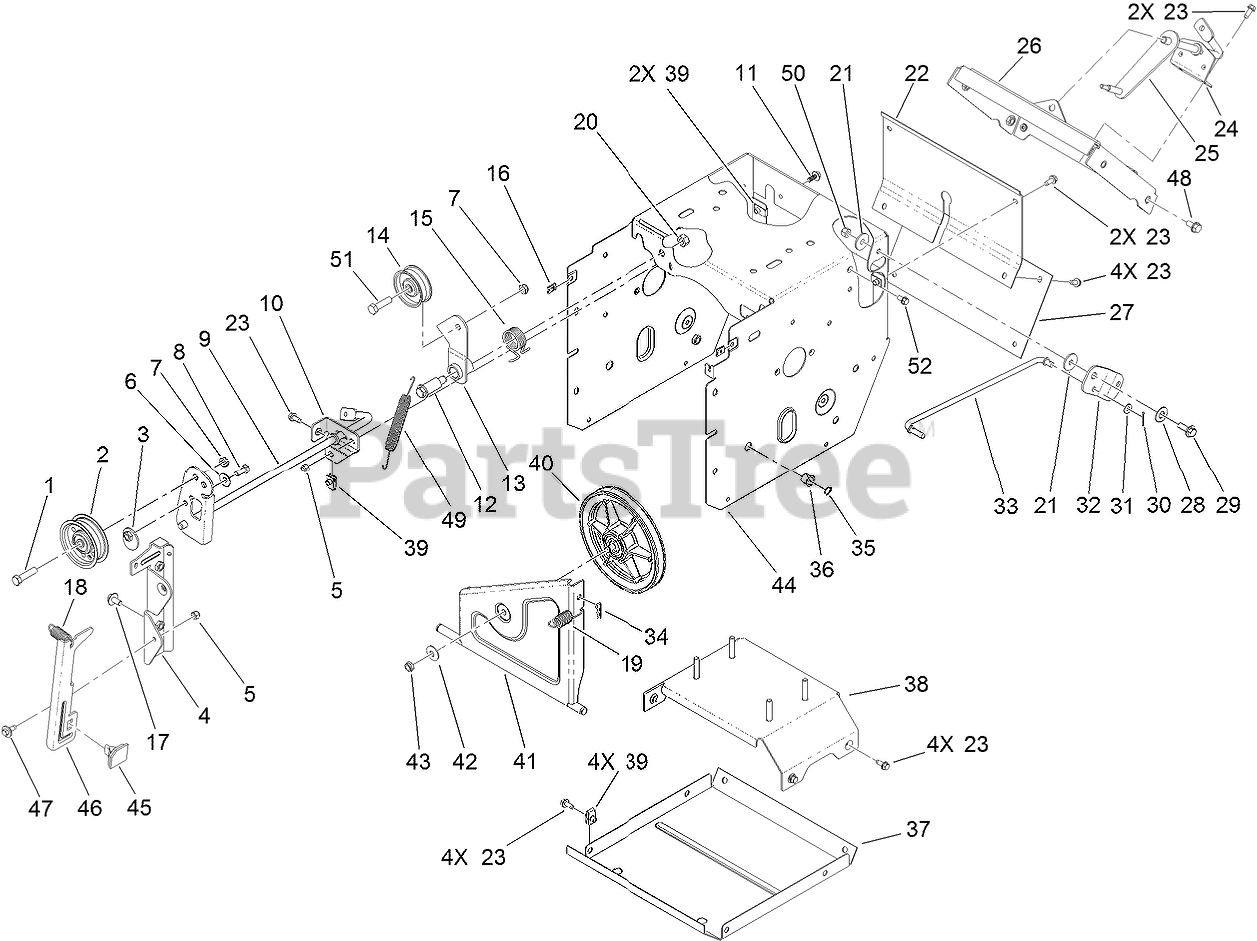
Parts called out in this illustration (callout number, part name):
1	SCREW-HH
2	PULLEY-IDLER
4	BRACKET-IDLER, IMPELLER
5	NUT-LOCK, NI
6	WASHER-BELLEVILLE
7	NUT-LOCK, NI
8	SCREW-HH
9	IMPELLER CLUTCH ASM
10	BRACKET-CLUTCH, IMPELLER
11	SCREW-HHF
12	BOLT-SHOULDER
13	ARM-IDLER, TRACTION
14	PULLEY-IDLER
15	SPRING-TORSION
16	NUT-SPEED, U-TYPE
17	SCREW-HHF
18	SPRING-EXTENSION
19	SPRING-EXTENSION
20	NUT-LOCK, NI
21	WASHER-PIVOT
22	COVER-UPPER
23	SCREW-HWH
24	BRACKET-ROD, SHIFT
25	LEVER-CONTROL, TRACTION
26	SHIFT PLATE ASM
27	COVER-LOWER
28	WASHER
29	SCREW-SHOULDER
30	PIN-COTTER
31	WASHER-PLAIN
32	BELLCRANK-DRIVE
33	LINK-CONTROL, SPEED
34	PIN-COTTER
35	RING-RETAINING
36	BUSHING-NYLINER
37	PAN-BOTTOM
38	FRAME BRACE ASM
40	PULLEY-TRACTION
41	BRACKET-WHEEL, FRICTION
42	WASHER-BELLEVILLE
43	NUT-HEX
44	FRAME-TRACTION
45	PAD-BRAKE
46	ARM-BRAKE
47	SCREW-SHOULDER
48	SCREW-HWHTF
49	SPRING-EXTENSION
50	NUT-LOCK, NI
51	SCREW-HH
52	SCREW-HWH
